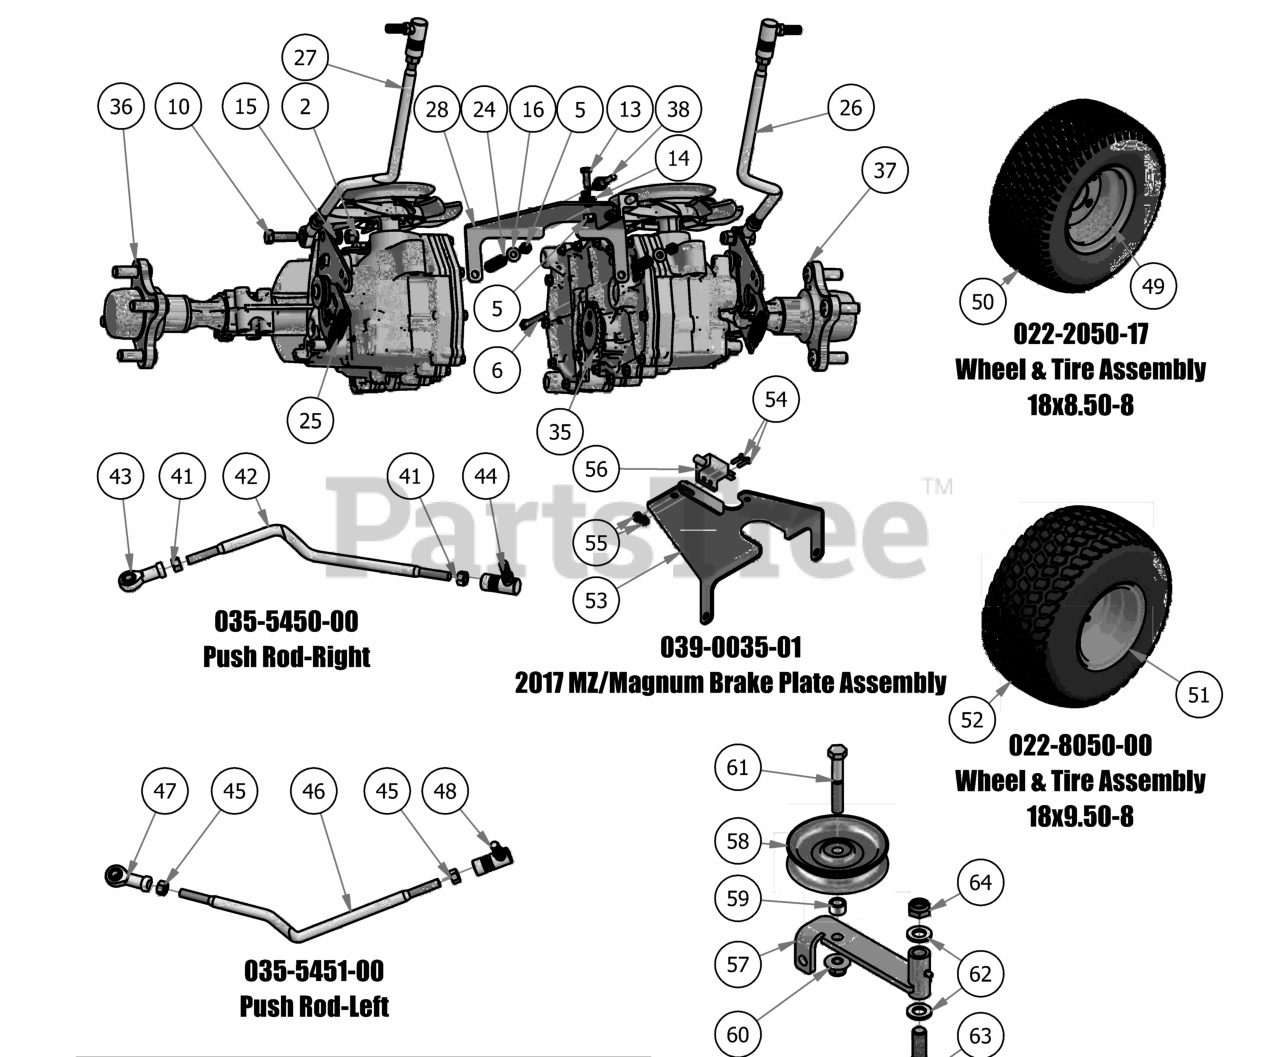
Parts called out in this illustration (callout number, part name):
2	3/8 Nylock Nut
5	1/4 Nylock Nut
6	1/4-20 x2-1/2 Gr2 hex C/s zinc
10	3/8" x 1 1/4" Hex Bolt
13	1/4" x 3/4" Hex Bolt
14	.390 x .750 x .062 Nylon Washer
15	3/8" Lock Washer
16	1/4" Flat Washer
24	Brake Spring
25	Gold Transaxle Spring
26	Push Rod-Right
27	Push Rod-Left
28	2017 MZ/Magnum Brake Plate Assembly
35	MZ Brake Cog Kit (Sold as Kit Only)
36	2017 MZ Right Transaxle
37	2017 MZ Left Transaxle
38	MZ Brake Cable
41	3/8" Fine Threaded Jam Nut
42	Push Rod - Right
43	Spherical Rod End - Outlaw
44	Quick Release Ball Joint
45	3/8" Fine Threaded Jam Nut
46	Push Rod - Left
47	Spherical Rod End - Outlaw
48	Quick Release Ball Joint
49	Wheel, 8.50-8, 42" MZ
50	Tire, 18x8.50-8, 42" MZ
51	rear rim for a 48in
52	18 x 9.50 - 8 Tire Only MZ
53	2017 MZ Brake Lock Bracket
54	10-24 X 5/8 BS Button Head Bolt
55	#10 Nylock Nut
56	Safety Switch
57	Pump Idler Bracket
58	4 3/4" Idler Pulley
59	1/2 x 1/2 Spacer
60	1/2-13 Nylon Flange Nut
61	1/2 x 2-3/4 Hex Bolt
62	.630 ID Plastic Washer
63	5/8" x 4" Hex Bolt
64	5/8" Nylock (1/2 Jam)
